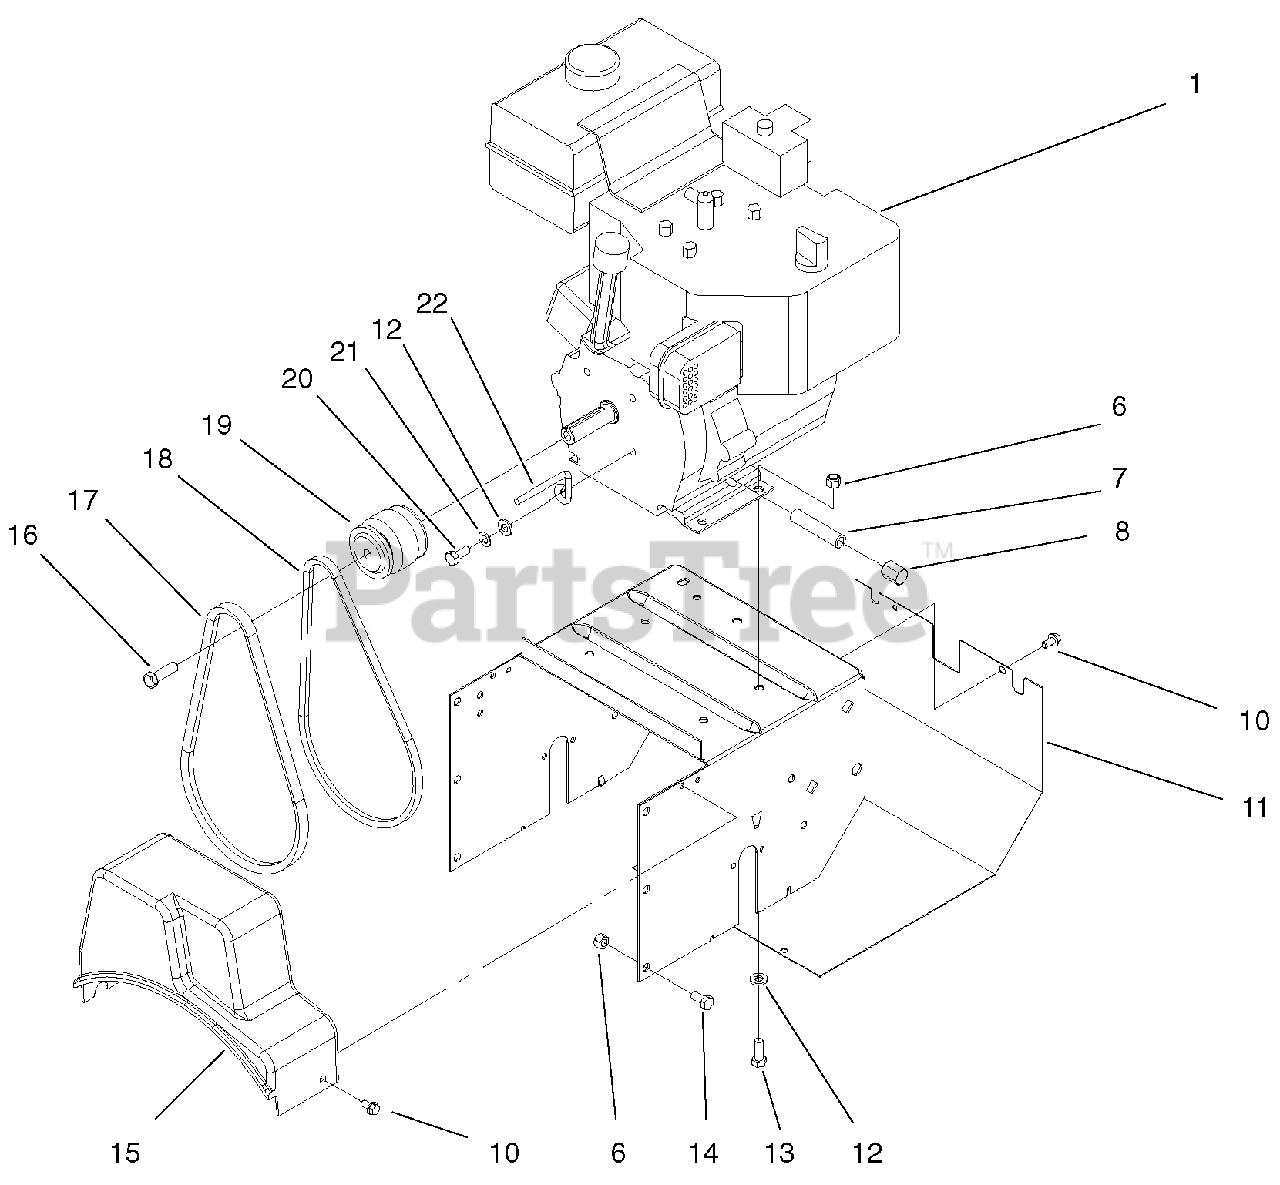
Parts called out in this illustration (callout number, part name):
6	Nut-Lock
7	Pipe-Nipple
8	Cap-Pipe
10	Screw-HH
11	Cover-Traction, Lower
12	Washer-Flat
13	Screw-HH
14	Screw-HH
15	Cover-Belt
16	Screw-Special
19	Pulley-Engine
20	Screw-HH
21	Washer-Lock/Ext
22	Retainer-Belt
